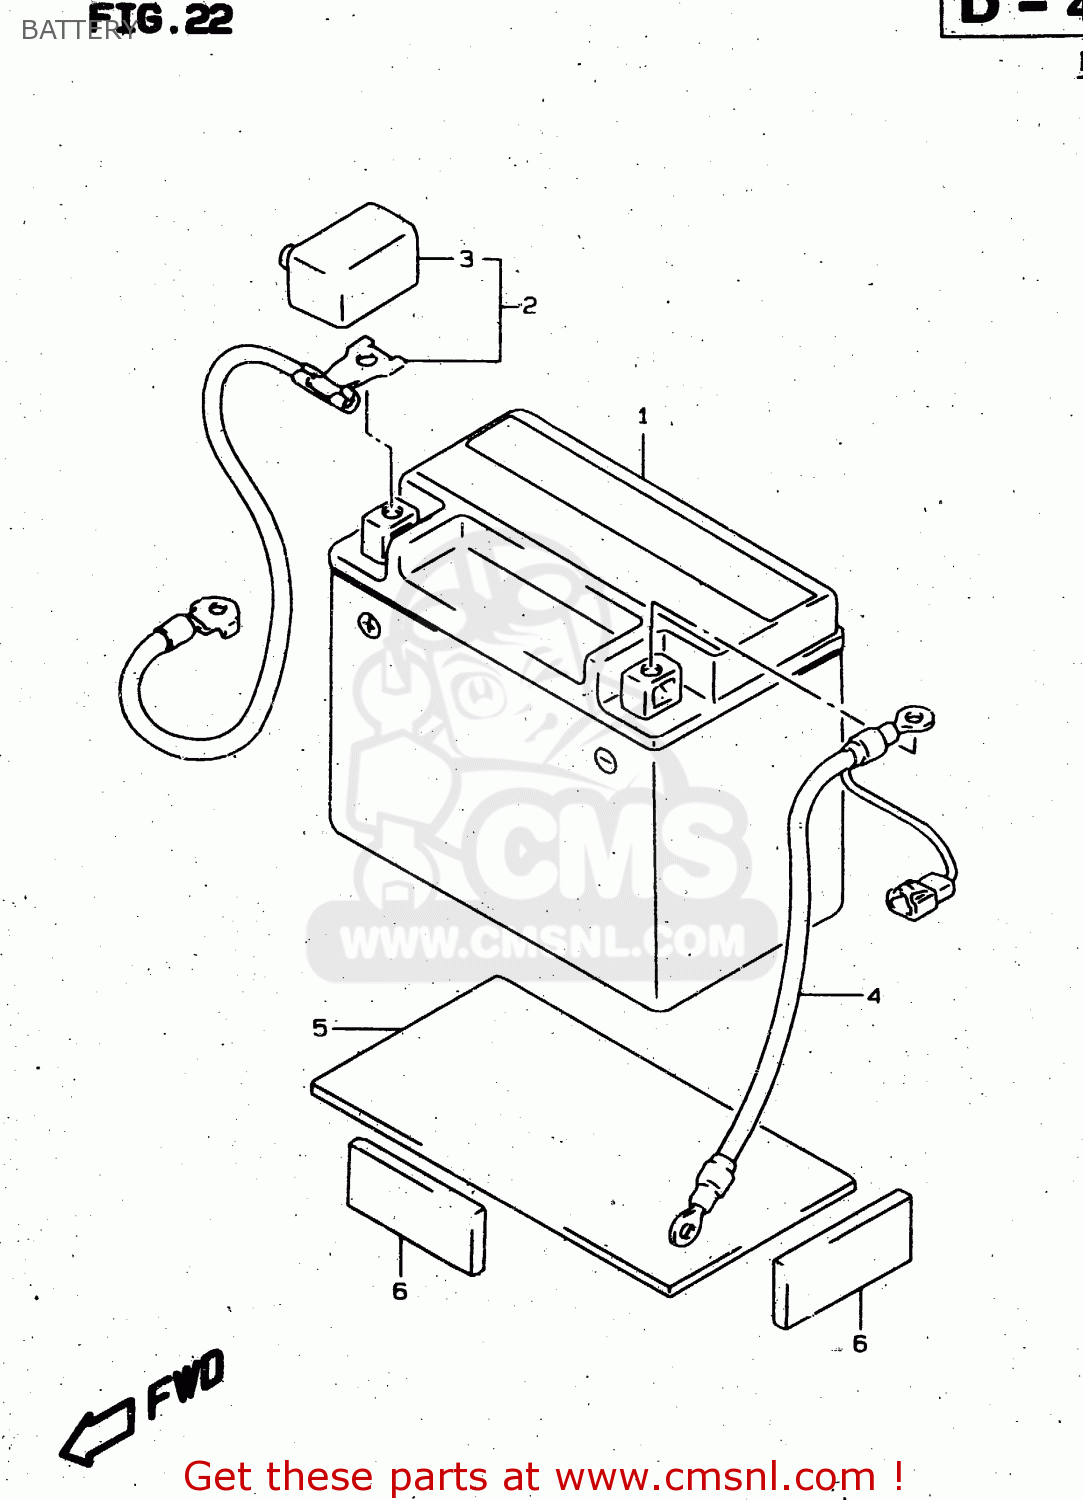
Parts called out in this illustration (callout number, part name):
1	BATTERY ASSY(YTX9-BS,12V8AH)
2	WIRE,BATTERY PLUS
3	CAP,BATTERY PLUS TERMINAL
4	WIRE,BATTERY MINUS
5	PROTECTOR(170X95X3.0)
6	CUSHION 20X45X6
